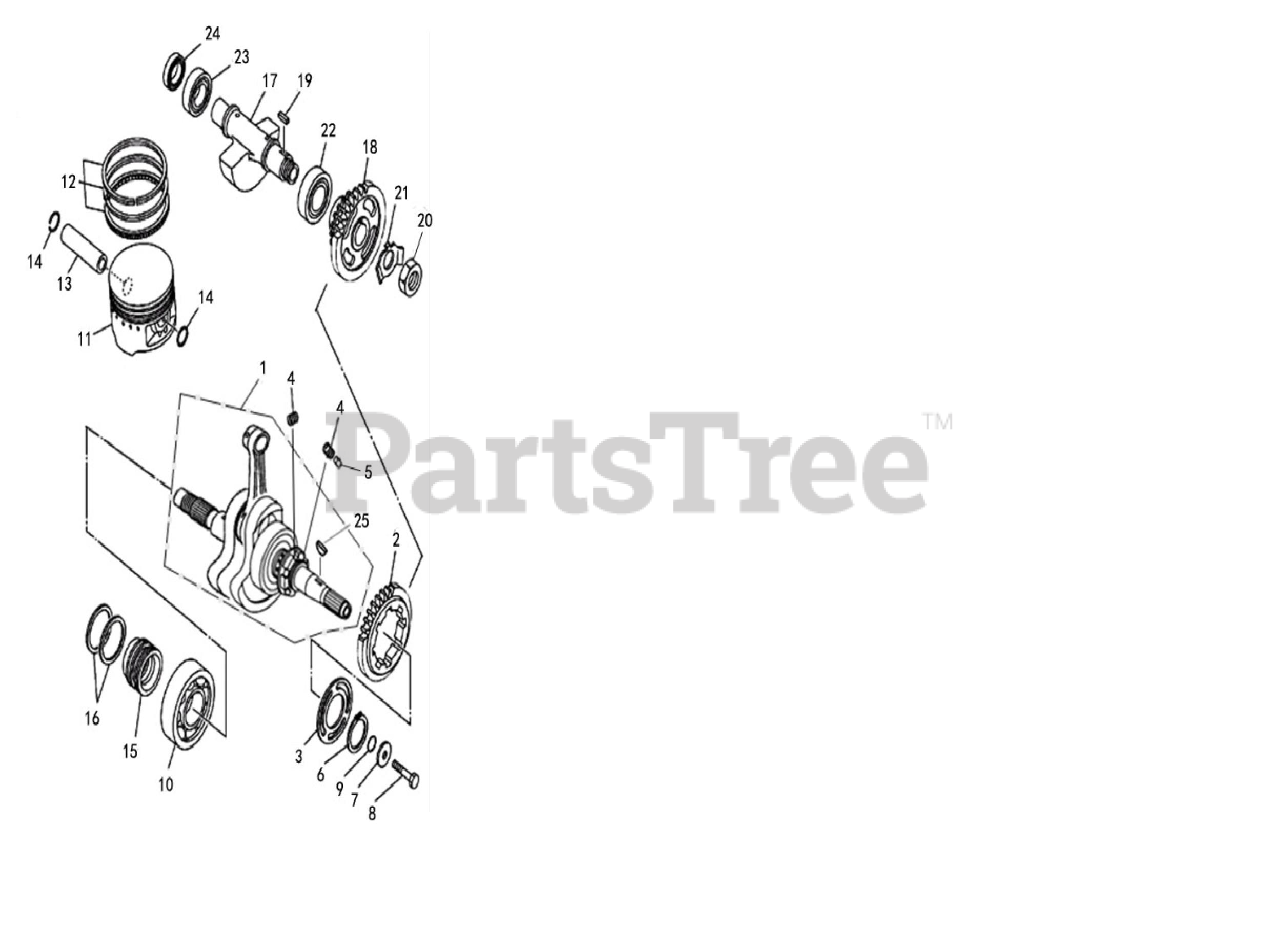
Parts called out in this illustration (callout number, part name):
1	CRANKSHAFT ASSEMBLY
2	Driving Gear,Balance Shaft
3	Locating Plate,Balance Gear,Outer
4	BALANCE GEAR BUFFER SPRING
5	Spacer Pin,Balance Gear
6	Circlip for shaft ?35
7	WASHER 10 X 32 X 5
8	BOLTS HEXAGON FLANGE M10 X 1.25 X 40
9	O-Ring 16X3
10	Bearing 6307
12	PISTON RING SET
13	PISTON PIN
14	PISTON PIN CLIP
15	Bushing,Sealing Ring
16	Sealing Ring
17	BALANCE SHAFT ASSEMBLY
18	DRIVEN GEAR BALANCE SHAFT ASSEMBLY
20	Hex Nut M18X1
21	Tab Washer A
22	Bearing 6305
23	Bearing 6304
24	Oil Seal 20X30X7
25	Key
